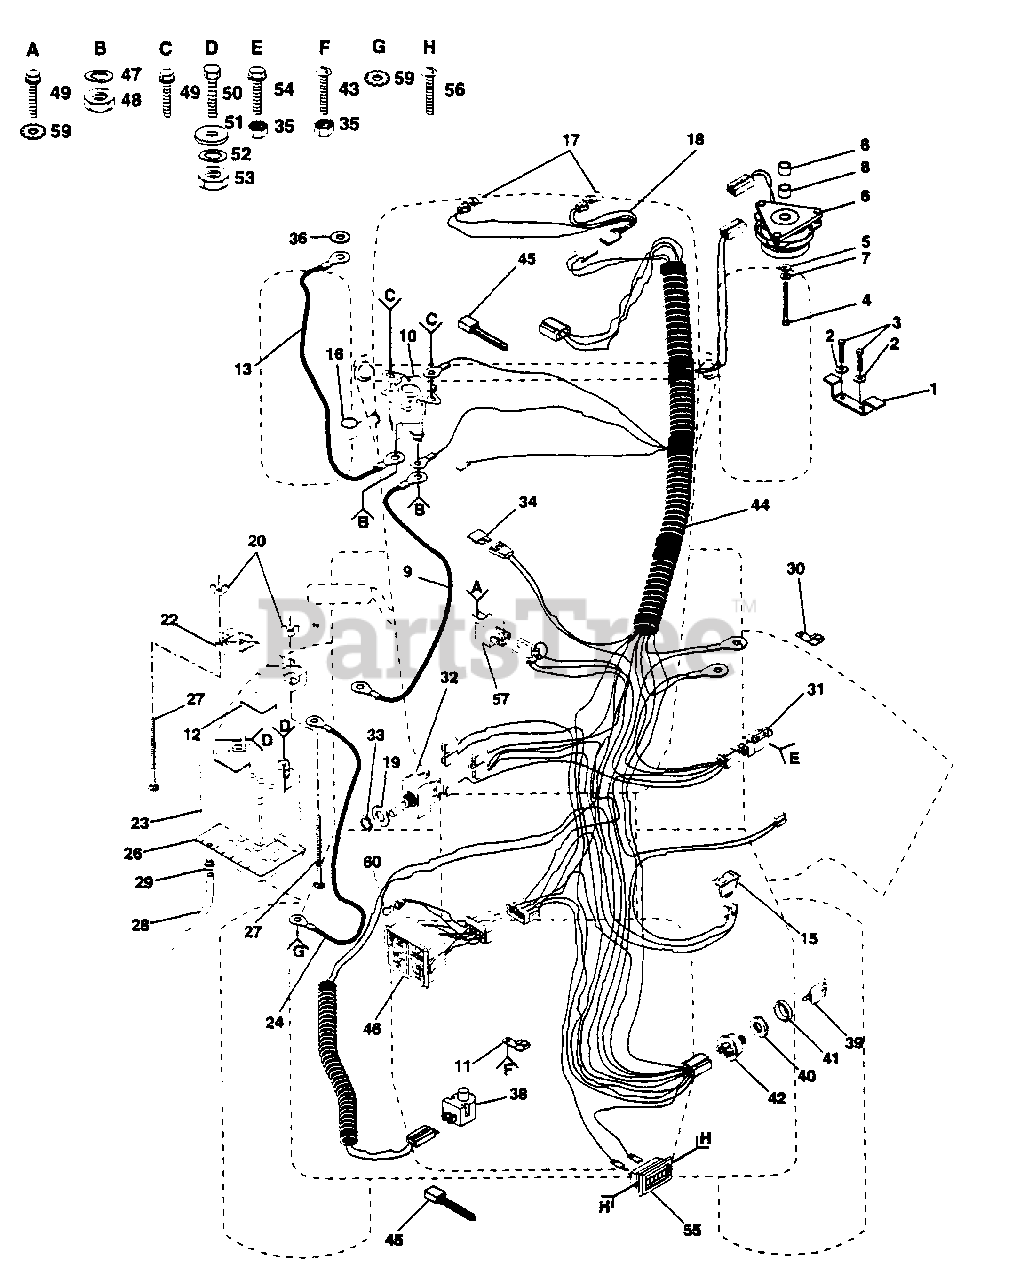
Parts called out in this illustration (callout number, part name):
1	Stop, Clutch (AYP part number)
2	Washer, Lock 3/8 (AYP part number)
3	Bolt, Hex 3/8-16 x 3/4 (AYP part number)
4	Bolt, Hex 7/16-20 x 1-1/2 Gr. 5
5	Washer (AYP part number)
6	Clutch, Electric (AYP part number)
7	Washer, Lock 7/16 (AYP part number)
8	Spacer, Clutch (AYP part number)
9	Cable, Battery (AYP part number)
10	Solenoid (AYP part number)
11	Clip, Insulated (AYP part number)
12	Battery, Caps (AYP part number)
13	Cable, Starter (AYP part number)
15	Switch, Light (AYP part number)
16	Cover, Terminal (AYP part number)
17	Bulb, Light (AYP part number)
18	Harness, Light Socket (AYP part number)
19	Washer, Lock External Tooth 1/4 (AYP part number)
20	Nut, Wing 1/4-20 (AYP part number)
21	Washer 17/32 x 3/4 x 16 Ga. (AYP part number)
22	Guard, Terminal (AYP part number)
23	Battery (AYP part number)
24	Cable, Ground (AYP part number)
26	Tray, Battery (AYP part number)
27	Bolt, Carriage 1/4-20 x 7-1/2 (AYP part number)
28	Tube, Plastic (AYP part number)
29	Clamp, Hose (AYP part number)
30	Clip (AYP part number)
31	Switch, Interlock (AYP part number)
32	Switch, P.T.O.
33	Nut, Hex (AYP part number)
34	Fuse (AYP part number)
35	Nut, Keps #10-32 (AYP part number)
38	Switch, Seat (AYP part number)
39	Key (AYP part number)
40	Nut, Ignition (AYP part number)
41	Bezel, Ignition (AYP part number)
42	Switch, Ignition (AYP part number)
43	Screw, Slot, Pan Head #10-33 x 1/2 (AYP part number)
44	Harness, Ignition (AYP part number)
45	Cable, Tie (AYP part number)
46	Light Package (AYP part number)
47	Washer, Lock 1/4 (AYP part number)
48	Nut, Hex Jam 1/4-20 (AYP part number)
49	Screw, Hex Washer Hd. Cutting 1/4-20 x 1/2 (AYP part number)
50	Bolt, Hex Hd. 1/4-20 x 3/4 (AYP part number)
51	Washer 9/32 x 5/8 x 16 Gauge (AYP part number)
52	Washer, Lock 1/4 (AYP part number)
53	Nut, Hex 1/4-20 (AYP part number)
54	Screw, Hex Washer Hd. #10-32 x 1-1/2 (AYP part number)
55	Meter, Hour (AYP part number)
56	Screw #10-24 x 1/2 (Black) (AYP part number)
57	Assembly, Relay (AYP part number)
59	Washer, Lock External Tooth 3/8 (AYP part number)
60	Bulb, Dashboard Light (AYP part number)
